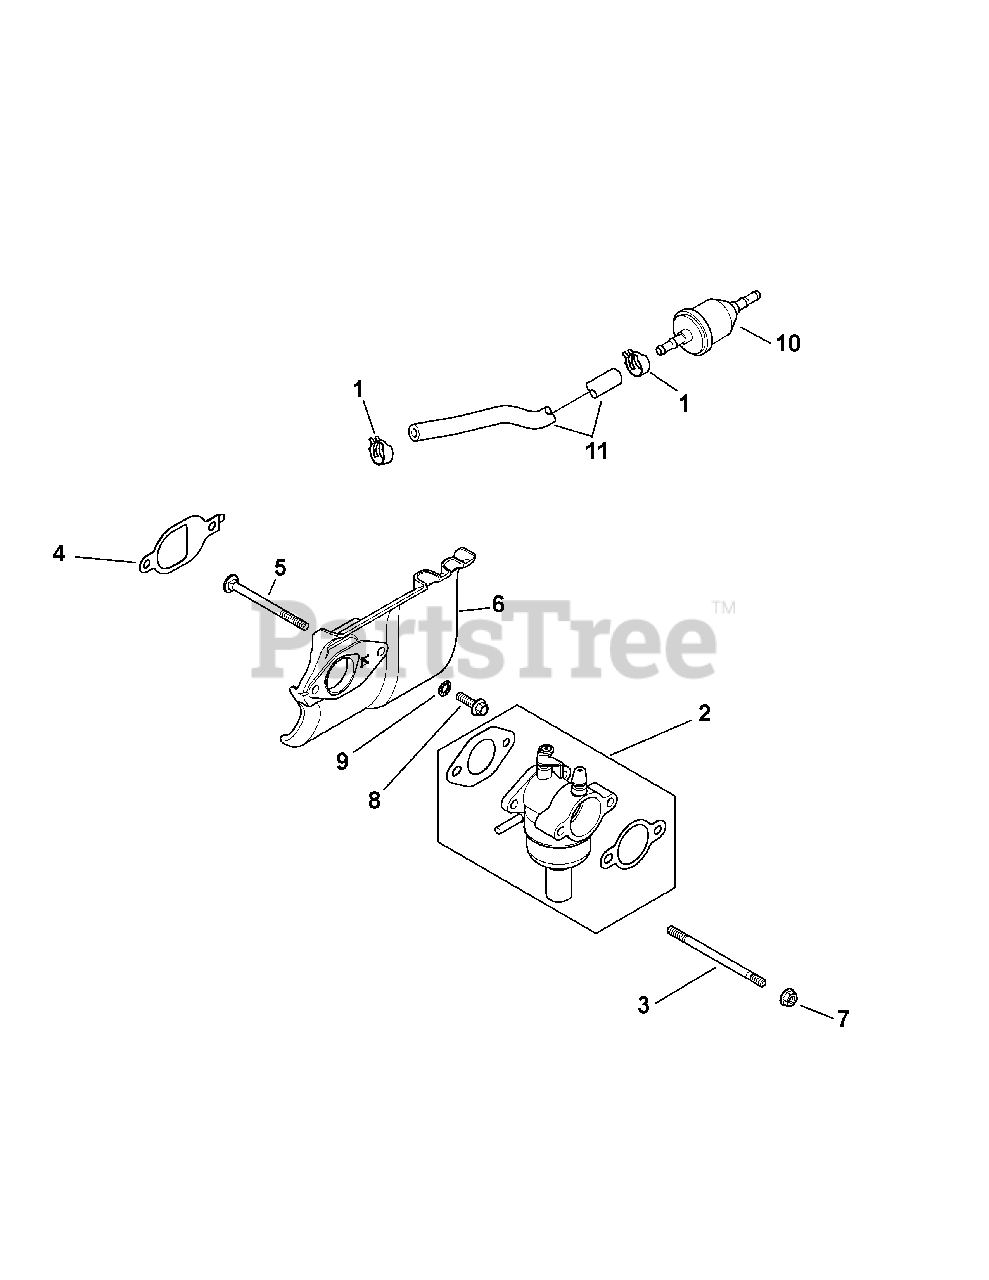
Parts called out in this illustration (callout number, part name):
1	Hose Clamp, 1/2
2	Carburetor Kit
3	Stud, M6 X 1.0 X 100
4	Heat Deflector Gasket
5	Carburetor Stud
6	Heat Deflector Kit
7	Flange Nut, M6 X 1.0
8	Flange Screw, M6 X 1.0 X 20
9	Int. Tooth Lock Washer, 1/4
